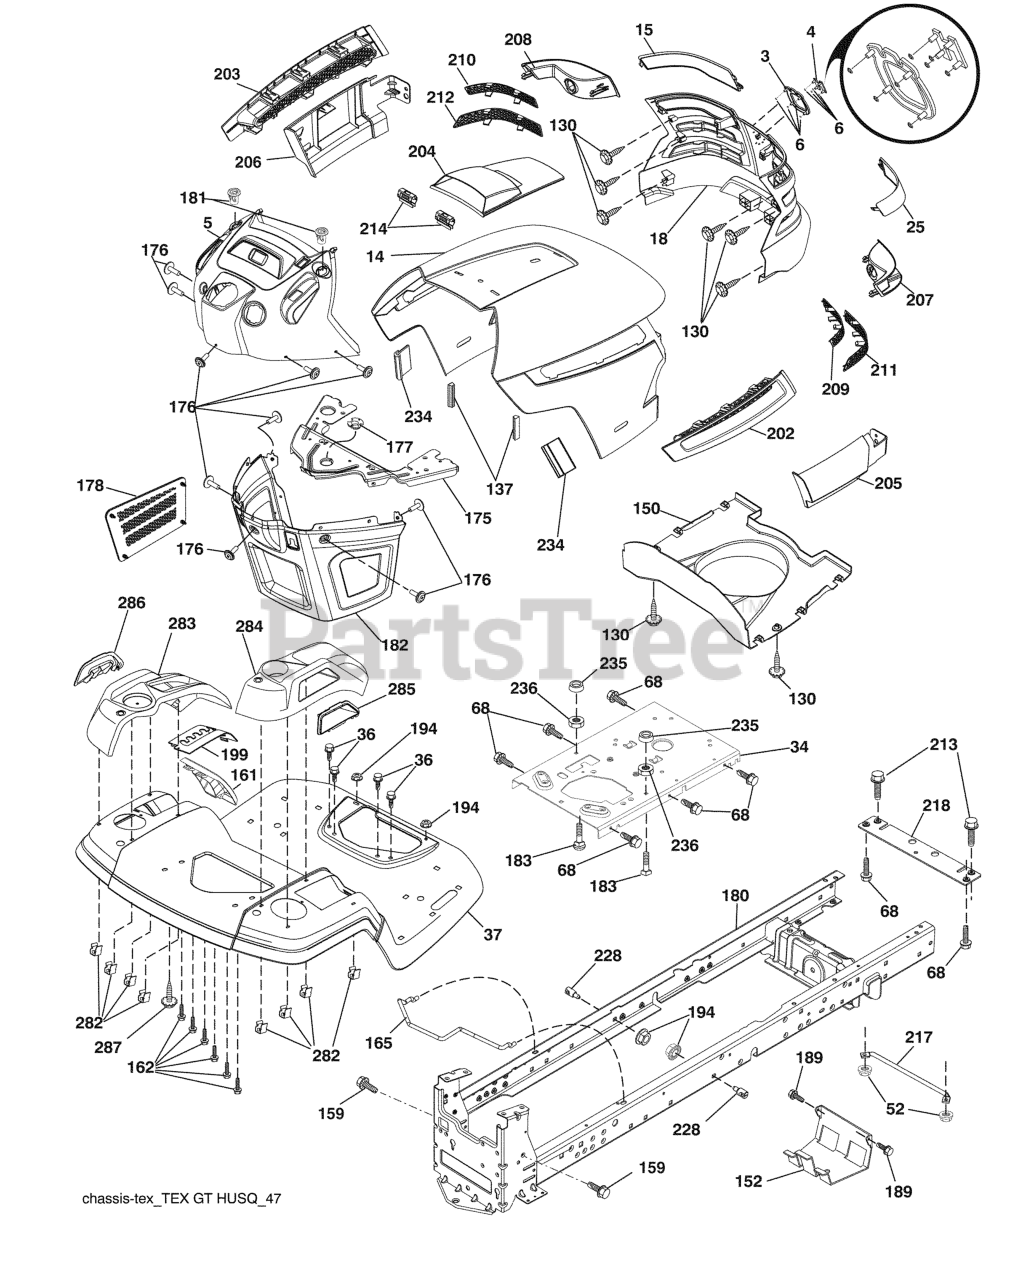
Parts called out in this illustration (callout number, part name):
3	TRIM.HUSQ.TG/CRD.SERVICE
4	RP LOGO
5	DASH ASM.HUSQ.GT.E.RDGA.N/CK.
6	NUT PUSH M
14	HOOD
15	LENS.LH.TEX.GT.HUSQ.CL
18	GRILL.ASM.HUSQ.TG/CRD.W/TRIM
25	LENS.RH.TEX.GT.HUSQ.CL
34	PLATE.ENGINE.WELDED.CHASSIS
36	SCREW 5/16"
37	FENDER.TLT.FS.W/CPH/FW/RSF.ORN
52	LOCKNUT
68	Screw Thdrol 5/16-18 x 1/2
130	SCREW.#10 X 0.750.BOS
137	BUMPER DASH
150	AIR.DUCT.HOOD.TEX.GT.HUSQ
152	SHIELD.BROWNING.W/TEX
159	SCREW, 3/8-16X3/4
161	WINDOW FUEL
162	SCREW.HI-LO.CONSOLE
165	SUPPORT.TANK.REAR.W/TEX
175	PLATE.CROSSMEMBER.HUSQ
176	SCREW.#10-24X5/8.RN.QU
177	BUSHING, STEERING
178	CARGO.ASM.NET.TXGT.W/C
180	CHASSIS
181	BUSHING.MNT.FEND.CRGO.
182	DASH.LOWER.COMMON.12V.ADAPTOR
183	BOLT.5/16-18X1-1/4 FULL.THREAD
189	SCREW
194	NUT LOCK HEX FLANGE 5/16-18
199	PLATE.DECK.LIFT.HUSQ.LT
202	VENT.SIDE.HOOD.HUSQ.RH.GREY
203	VENT.SIDE.HOOD.HUSQ.LH.GRAY
204	HOOD VENT
205	SKIRT.HOOD.SIDE.HUSQ.RH.GREY
206	SKIRT.HOOD.SIDE.HUSQ.LH.GREY
207	BEZEL.RH.TEX.GT.HUSQ
208	BEZEL.LH.TEX.GT.HUSQ
209	INSERT.HEX.GRILL.HUSQ.GREY
210	INSERT.HEX.GRILL.HUSQ.
211	INSERT.HEX.GRILL.HUSQ.
212	INSERT.HEX.GRILL.HUSQ.
213	BOLT
214	CLIP.RETAINER.TINNER.
217	ROD.PIVOT.HOOD
218	X-PIECE.HOOD.STOP.NON/
228	STUD.FASTNER.W/ANTI-ROTATE
234	BUMPER.HOOD.TEX.HUSQVARNA
235	SPACER FENDER
236	NUT.CENTERLOCK.5/16-
282	CLIP.RETAINER.CONSOLE.LT.HUSQ
283	CONSOLE.DECK.LFT.R.SDFL.HUSQLT
284	CONSOLE.CNTRL.
285	CONSOLE INSERT RH
286	CONSOLE.INSRT.LH.HUSQ.LT.BLACK
287	SCREW 1/4X20
